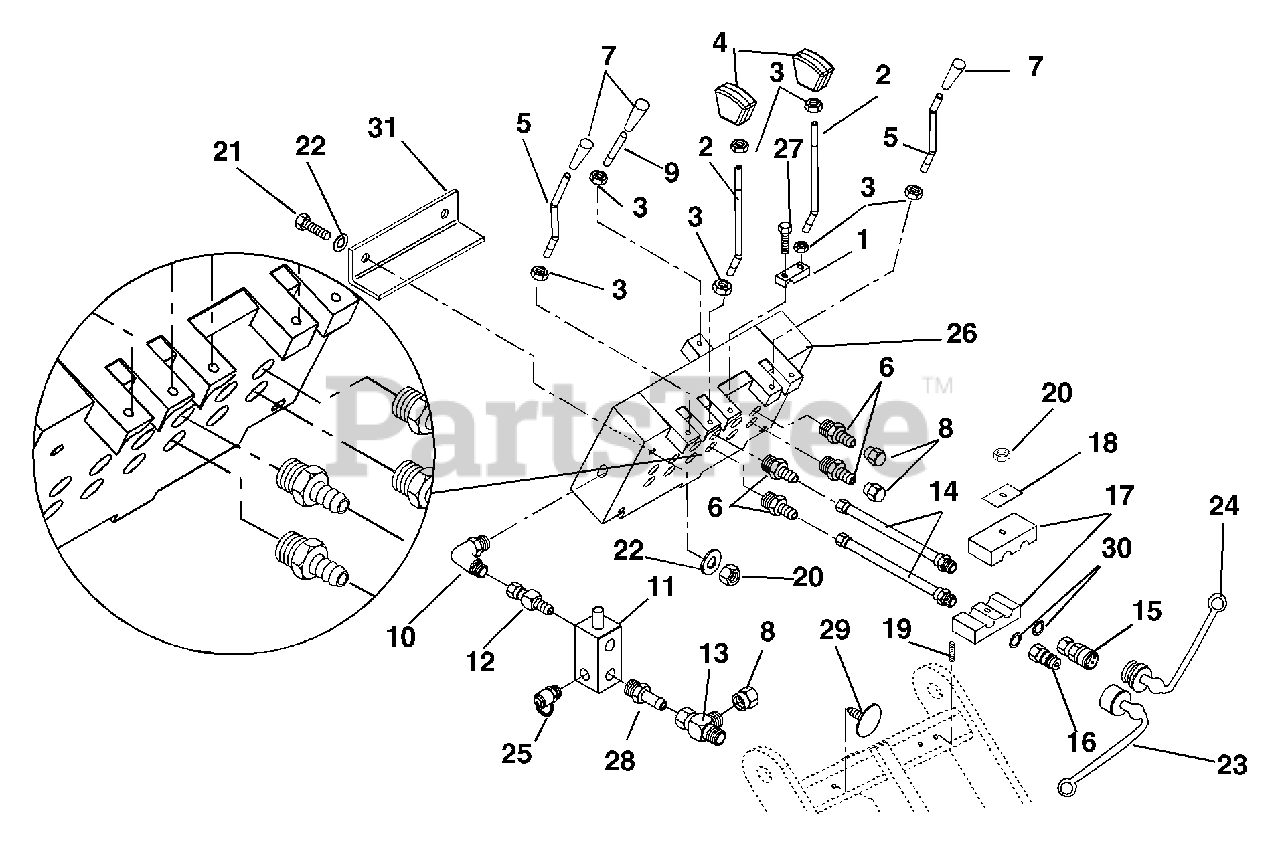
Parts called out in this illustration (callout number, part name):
1	Bracket-Positioner Lever
2	Lever-Direction Control
3	Nut-Jam M10-1.5
4	Knob-Control
5	Lever-Cylinder Control
6	Adapter-Straight .500-14M x .875-14M
7	Knob-Control Lever
8	Cap-Steel .88-14
9	Lever-Auxiliary Control
10	Adapter-90 Degree Elbow .500-14 x .750-16
11	Valve-Overcenter
12	Adapter-Swivel Connector .75-16 x .75-16
13	Adapter-Swivel Nut Run Tee .875-14
14	Hose-Hydraulic Auxiliary Power
15	Coupler-Female Quick .500-14
16	Coupler-Male Quick .500-14
17	Clamp-Dual Hose .500 I.D.
18	Plate-Cover
19	Stud 8mm-1.25 x 3.62
20	Nut-Locking-Nylon M8-1.25
21	Bolt-Hex M8-1.25 x 20
22	Washer-Flat-Steel .38 x .875 x .083
23	Plug-Dust .50
24	Cap-Dust .50
25	Coupling-Test Port
26	Valve-Bank
27	Bolt-Hex M10-1.5 x 30 Grade 5
28	Adapter-Straight .75-16 x .875-14
29	Retainer-Trim
30	Seal, Bonded
31	Shield, Valve Heat
